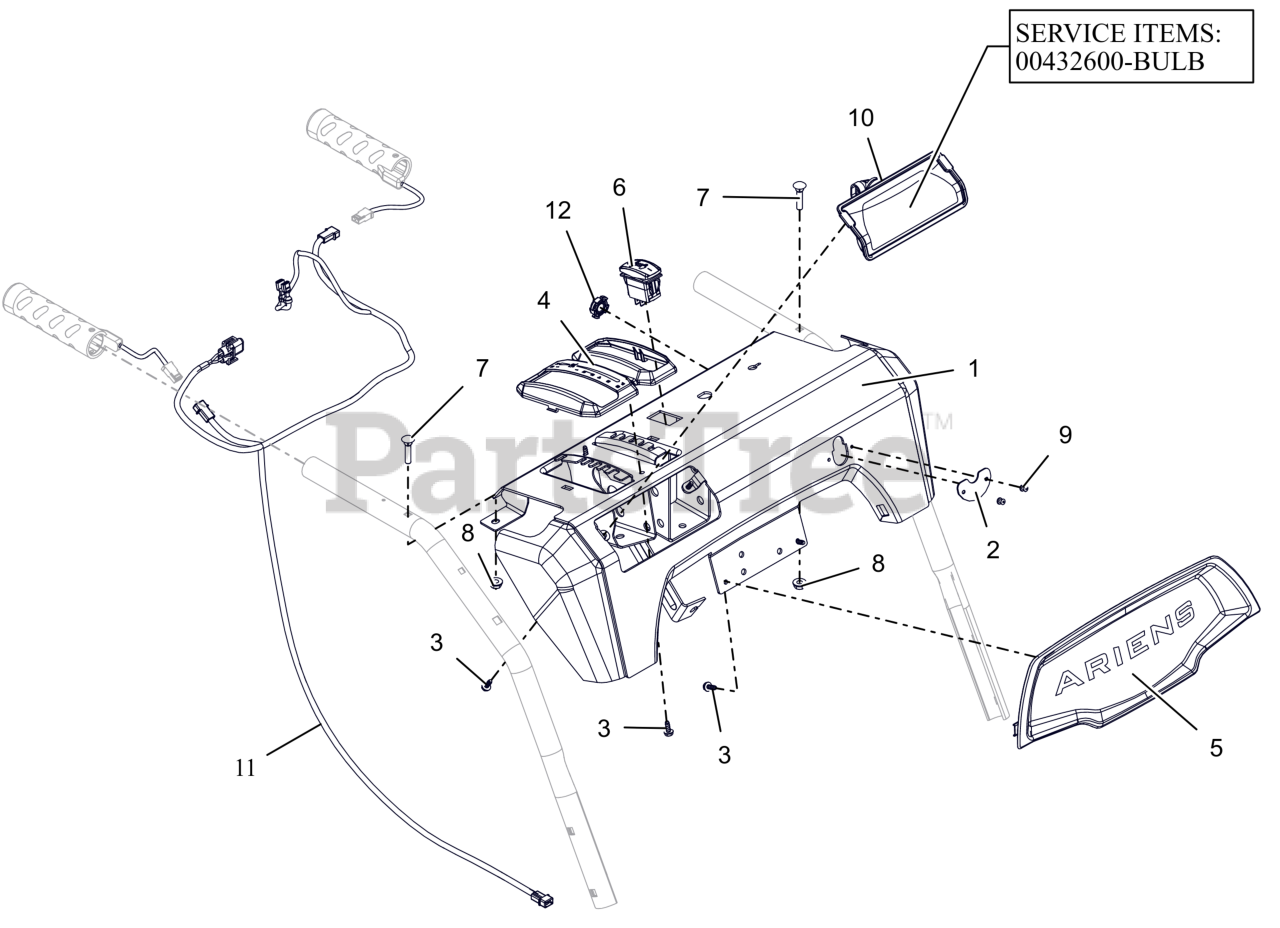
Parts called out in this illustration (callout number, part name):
1	CONTROL PANEL W/DECAL FRIC-ID
2	COVER, DASH BRKT, ID
3	SCR, PLASTIC #10X.50
4	BEZEL, SHIFT - FRICTION SNOW
5	BEZEL, DASH - ARIENS LG DASH
6	SWITCH,ROCKER SPST-ON/OFF
7	BLT-RDHDXLSQNK.25-20X1.25 G5ZC
8	NUT-LK-CTR-FLG .25-20 ZC120
9	RVT-POP #43 .125X.313 STL ZINC
10	HEADLIGHT ASY, HALO 20W 2SHOT
11	HARNESS, LIGHT & WARMER
12	CRANK BUSHING, NYLON CHUTE BK
